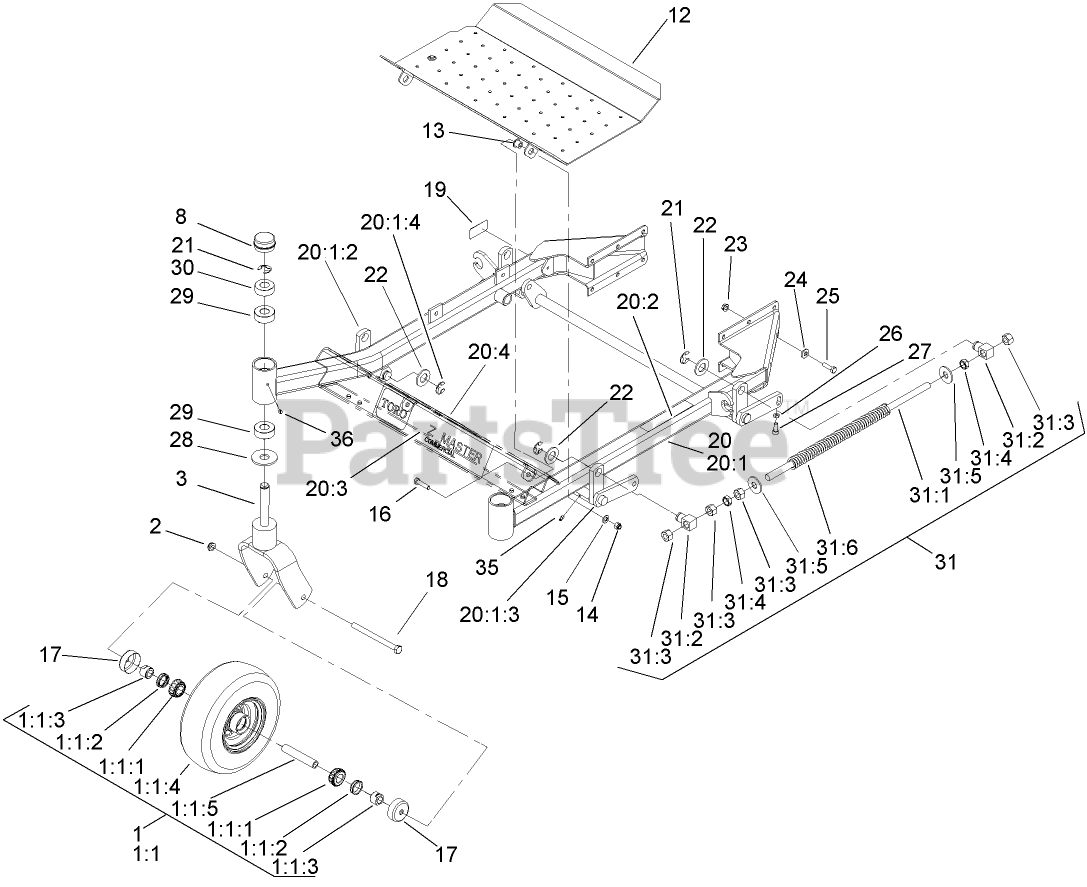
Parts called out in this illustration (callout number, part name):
1	WHEEL AND TIRE ASM
1:1	WHEEL AND BEARING ASM
1:1:1	BEARING-CONE, TAPER
1:1:2	SEAL-CASTER
1:1:3	SPACER-NUT
1:1:4	WHEEL AND TIRE ASM
1:1:5	AXLE-CASTER
2	NUT-LOCK, NI
3	CASTER FORK ASM
8	CAP-GREASE
12	FLOOR PAN
13	BUSHING-FLANGE
14	NUT-LOCK, NI
15	WASHER-FLAT
16	SCREW-HH
17	GUARD-SEAL
18	SCREW-HH
19	DECAL-STD, SAFETY
20	FRONT FRAME ASM
20:1	FRAME-FRONT
20:1:2	RH LIFT ARM ASM
20:1:3	LH LIFT ARM ASM
20:1:4	RING-RETAINING, EXT
20:2	DECAL-WARNING
20:4	DECAL-WARNING
21	RING-RETAINING, EXT
22	WASHER-FLAT
23	NUT-HHF, WHIZ
24	WASHER-BELLEVILLE
25	SCREW-HH
26	NUT-JAM
27	SCREW-HSH
28	SPACER-SUPPORT, DECK
29	BUSHING
30	SPACER
31	FRONT FRAME SPRING ASM
31:1	ROD-LIFT, DECK
31:2	SWIVEL-DECK MOUNT, REAR
31:3	NUT-HEX
31:4	NUT-JAM
31:5	WASHER-FLAT
31:6	SPRING-SUPPORT, DECK
35	FITTING-GREASE
36	FITTING-GREASE
